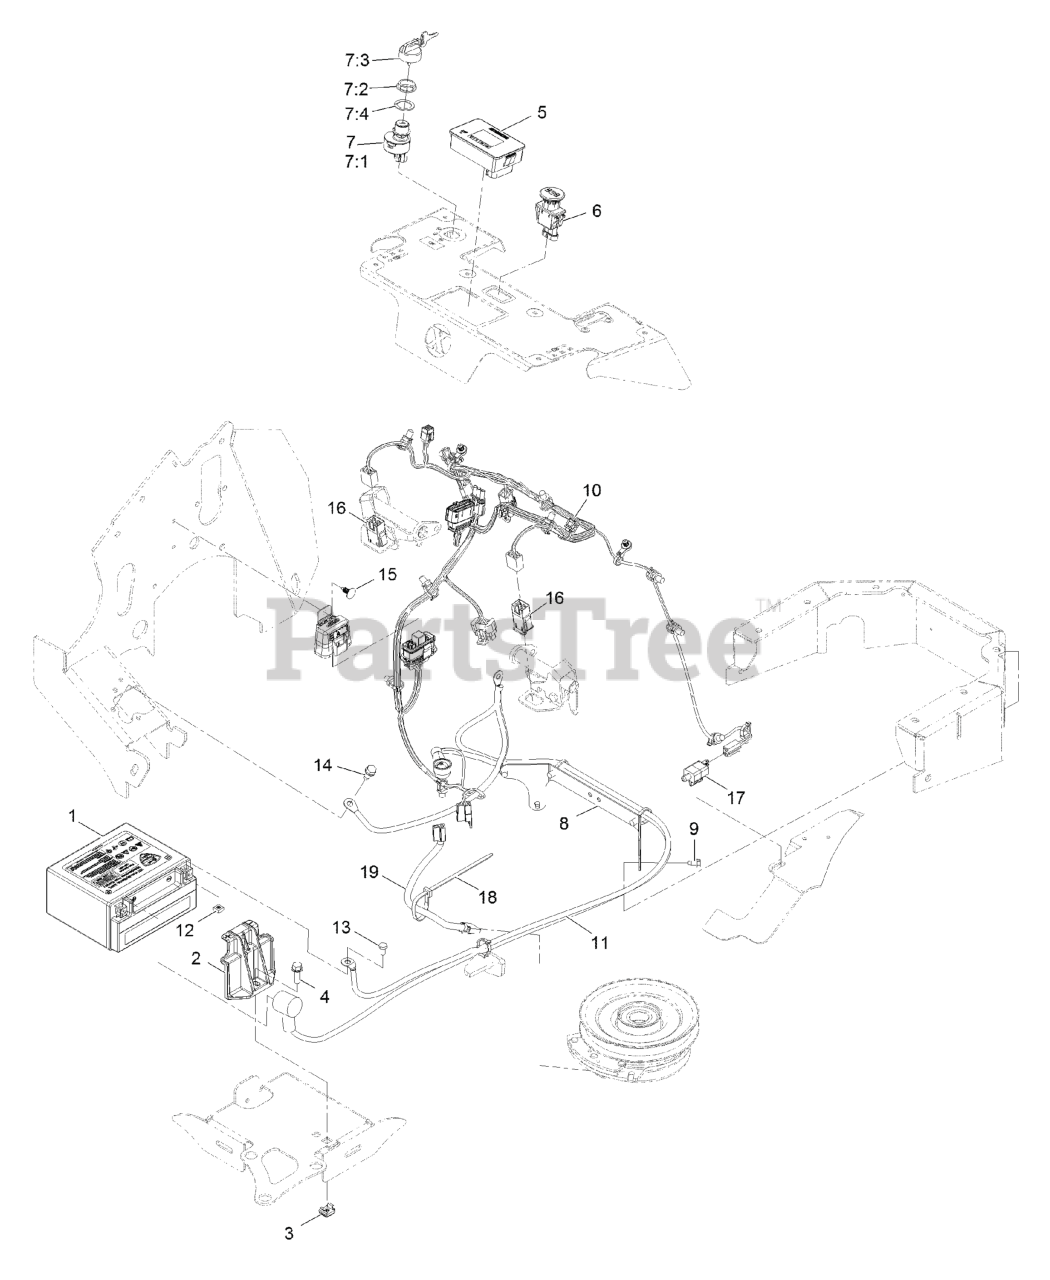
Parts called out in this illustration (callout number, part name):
1	Battery, Agm
2	Hold Down, Battery
3	Nut, Snap
4	SCREW-HHF
5	Meter-Hour
6	SWITCH-PTO, SEALED
7	IGNITION SWITCH ASM
7:1	Switch-Ignition
7:2	NUT-MOUNTING
7:3	IGNITION KEY SET
7:4	WASHER-BACKUP
8	Support, Battery Cable
9	SCREW-HWH
10	Harness-Wiring
11	Harness-Battery
12	Square Nut 1/4-20,ATV CB
13	SCREW-HH
14	SCREW-THD ROLL, HWH
15	PLUG-PLASTIC
16	SWITCH-DELTA
18	TIE-PLASTIC
19	HARNESS-CLUTCH PIGTAIL
